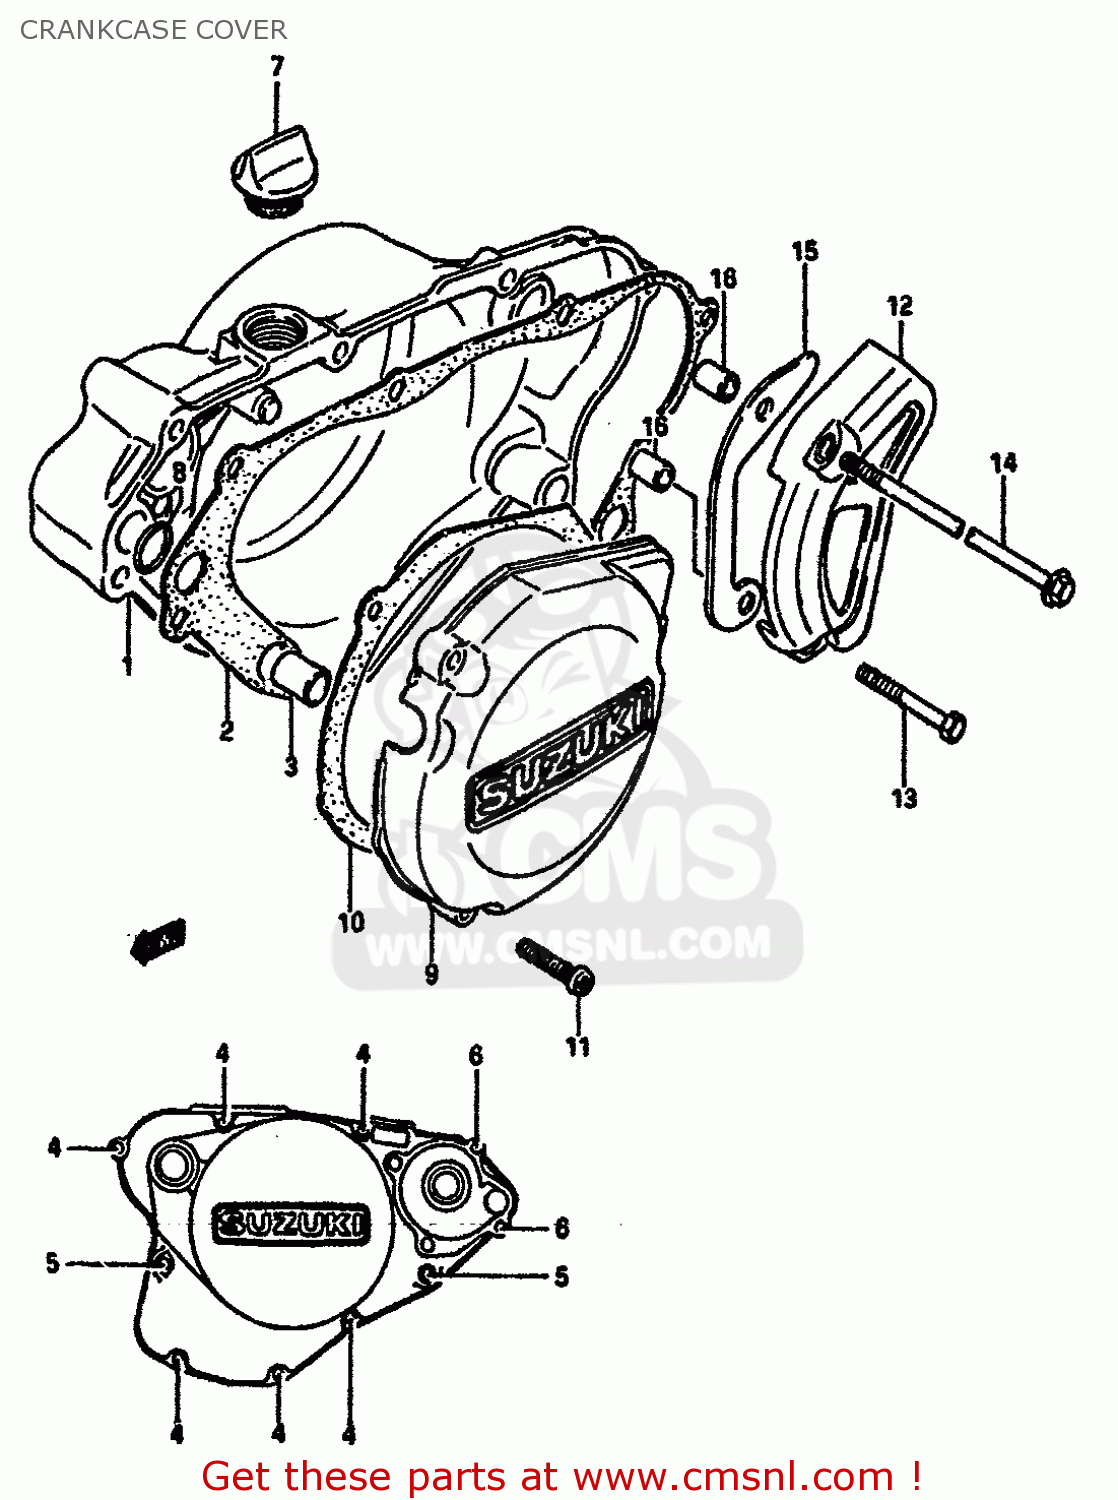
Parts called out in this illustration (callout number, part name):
1	COVER,CLUTCH
2	GASKET,CLUTCH COVER (MCA)
3	PIN
4	SCREW
5	SCREW
6	SCREW
7	PLUG SET
8	O RING(D:1.9,ID:14.5)
9	COVER,MAGNETO
10	GASKET,MAGNETO COVER (MCA)
11	SCREW
12	COVER,SPROCKET
13	BOLT
14	BOLT(6X105)
15	PLATE,CHAIN GUIDE
16	SPACER(6.5X10.5X12)
